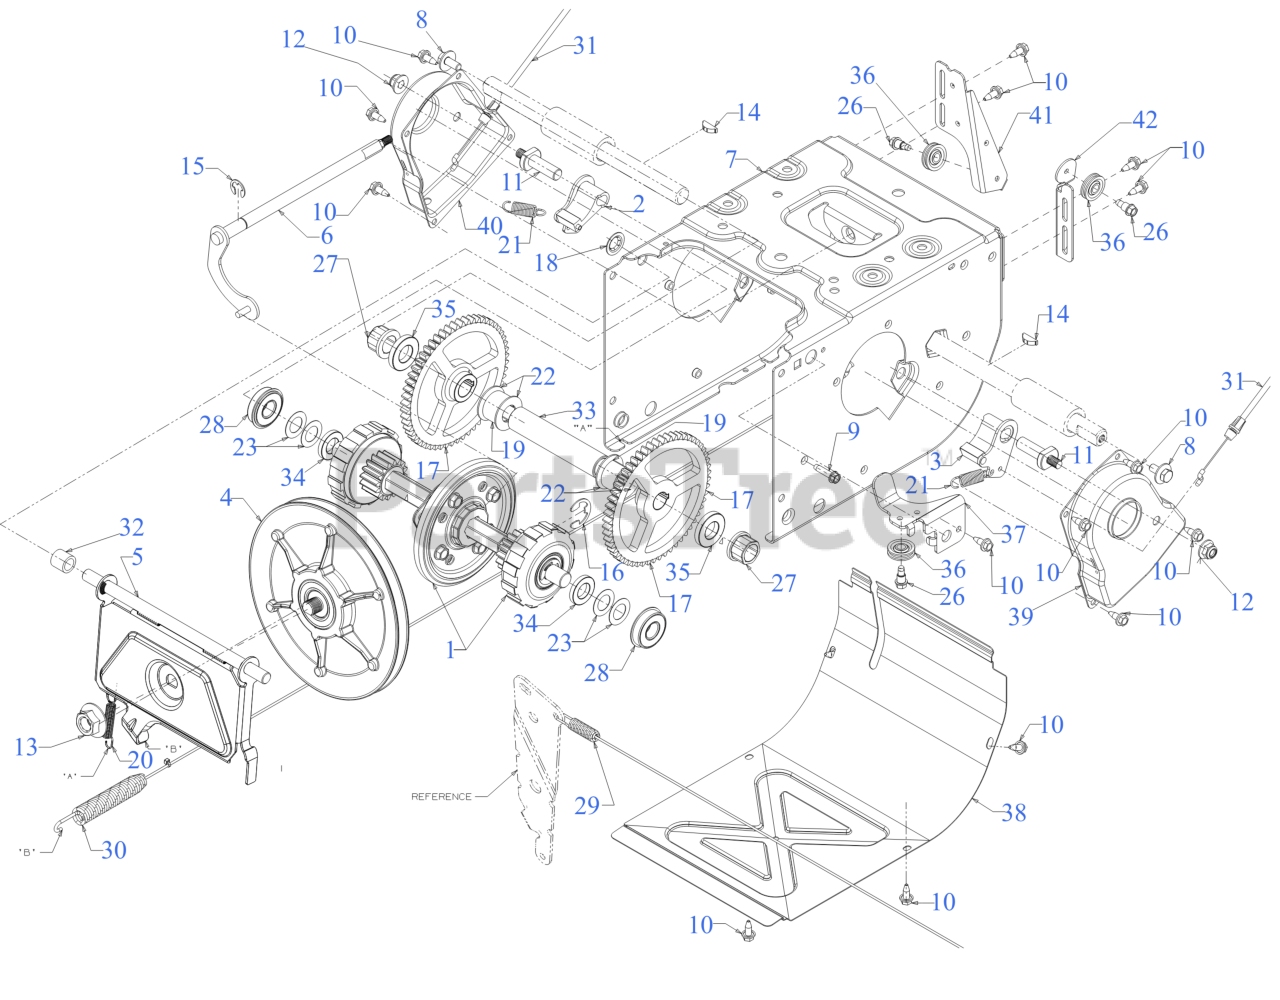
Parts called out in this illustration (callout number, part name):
1	PLANETARY FRICTION WHEEL HEX SHAFT
2	DOGG ASSEMBLY (RH)
3	DOGG ASSEMBLY (LH)
4	FRICTION WHEEL DISC ASSEMBLY
4	FRICTION DISC PIN
4	BALL BEARING
4	FRICTION DISC PULLEY 3LX8.27
5	FRICTION WHEEL BRACKET (POWDER BLACK)
6	SHIFT ROD ASSEMBLY
7	DRIVE FRAME
8	SCREW 5/16-24 x .750 GR5
9	SCREW 1/4-20 x 1.00
10	SCREW 1/4-20X.625
11	ACTUATOR SHAFT
13	FLANGE NUT 5/8-18
14	KEY 3/16 x 3/4
15	E-RING FOR .500 SHAFT
16	RETAINING RING
19	SPACER: .76ID x .75
20	EXTENSION SPRING
21	EXTENSION SPRING
22	FLAT WASHER
23	FLAT WASHER .67X 1.174X .02
26	SHOULDER SCREW
27	FLANGE BEARING
28	BALL BEARING W/RET
29	AUGER DRIVE CABLE 47.48"
30	WHEEL DRIVE CABLE 44.955"
31	STEERING CABLE
32	SPACER-.513 ID x .703 OD x .69
33	AXLE SUPPORT TUBE
35	AXLE SPACER
36	CABLE GUIDE ROLLER
37	AUGER CABLE BRACKET
41	CABLE GUIDE BRACKET (DRIVE)
42	CABLE GUIDE BRACKET (AUGER)
